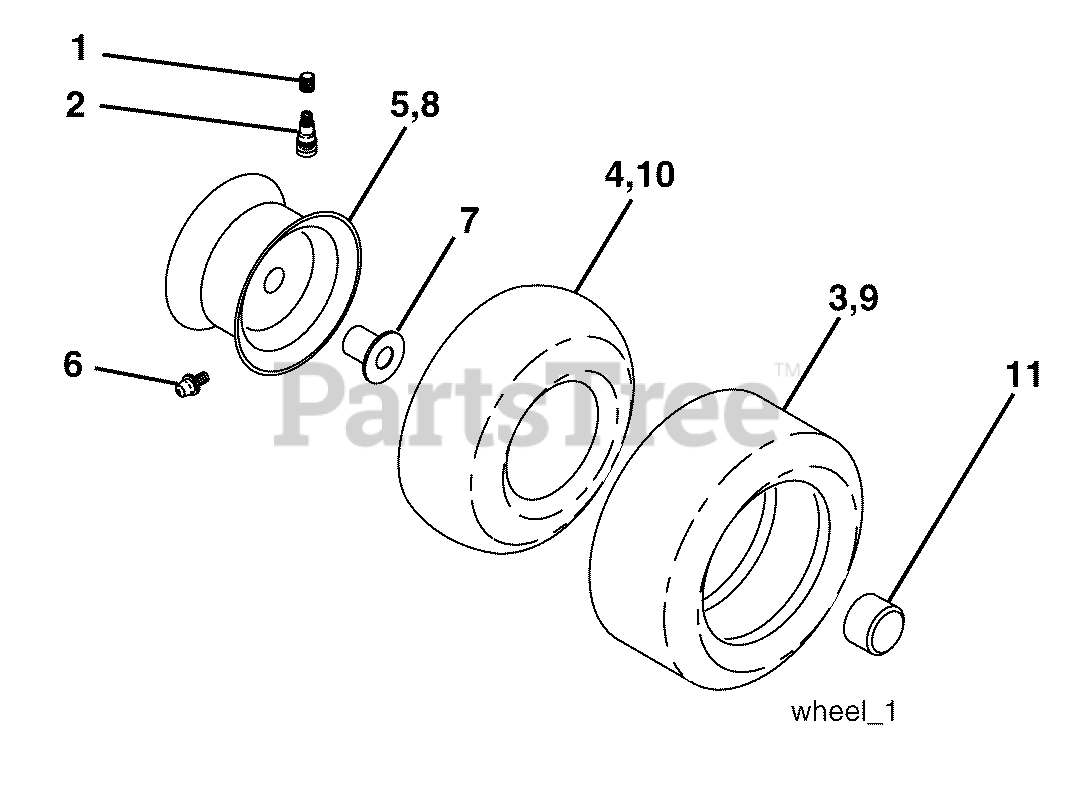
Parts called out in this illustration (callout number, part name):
1	Cap Valve Tire
2	Stem Valve
3	Tire F Ts 15 x 6 0 - 6 Service
4	Tube Front
5	Rim Asm 6"front Silver Service
6	Fitting Grease
7	Bearing Flange
8	Rim Asm 8"rear Silver Service
9	Tire R Ts 20 x 8-8 C Service
10	Tube Rear
11	Cap Axle Blk 1 50 x 1 00
